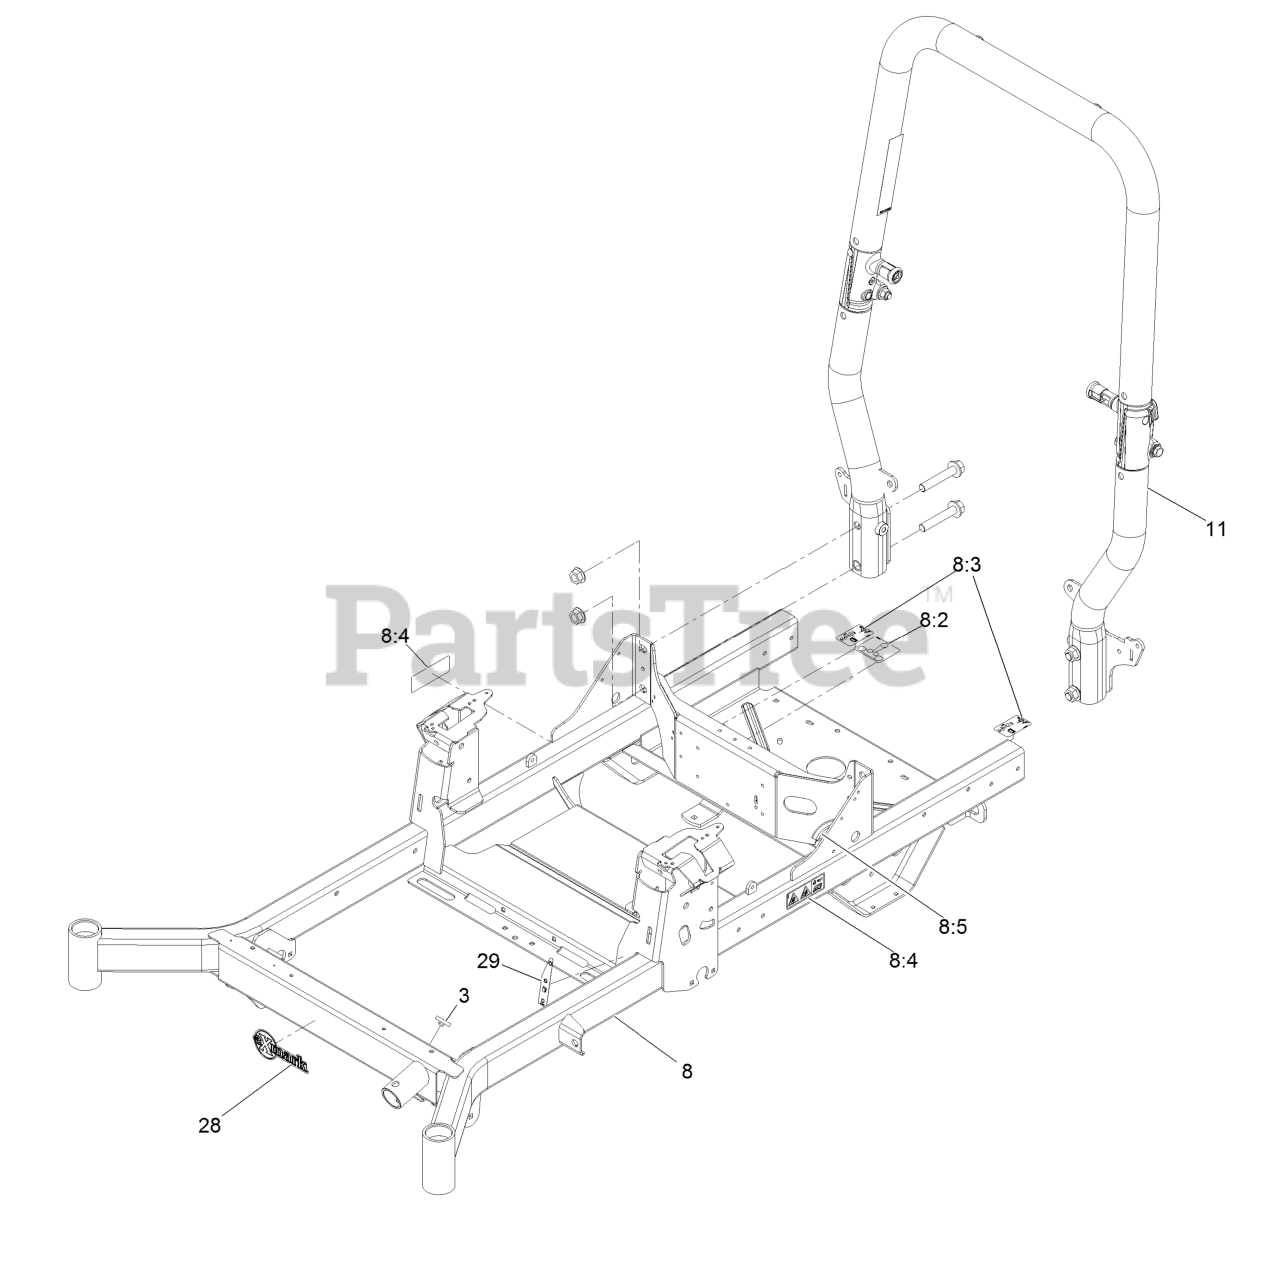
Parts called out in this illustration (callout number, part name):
3	Bumper-Push-In, Rubber
8	Frame-60Rd,Suspension
8:2	Decal-Routing, Belt
8:3	Decal-Release, Drive
8:4	Decal-Warning
8:5	Strip-Seal
11	ASM-ROPS Tapered
28	Decal-Exmark Logo
29	Decal-Fill, Fuel
